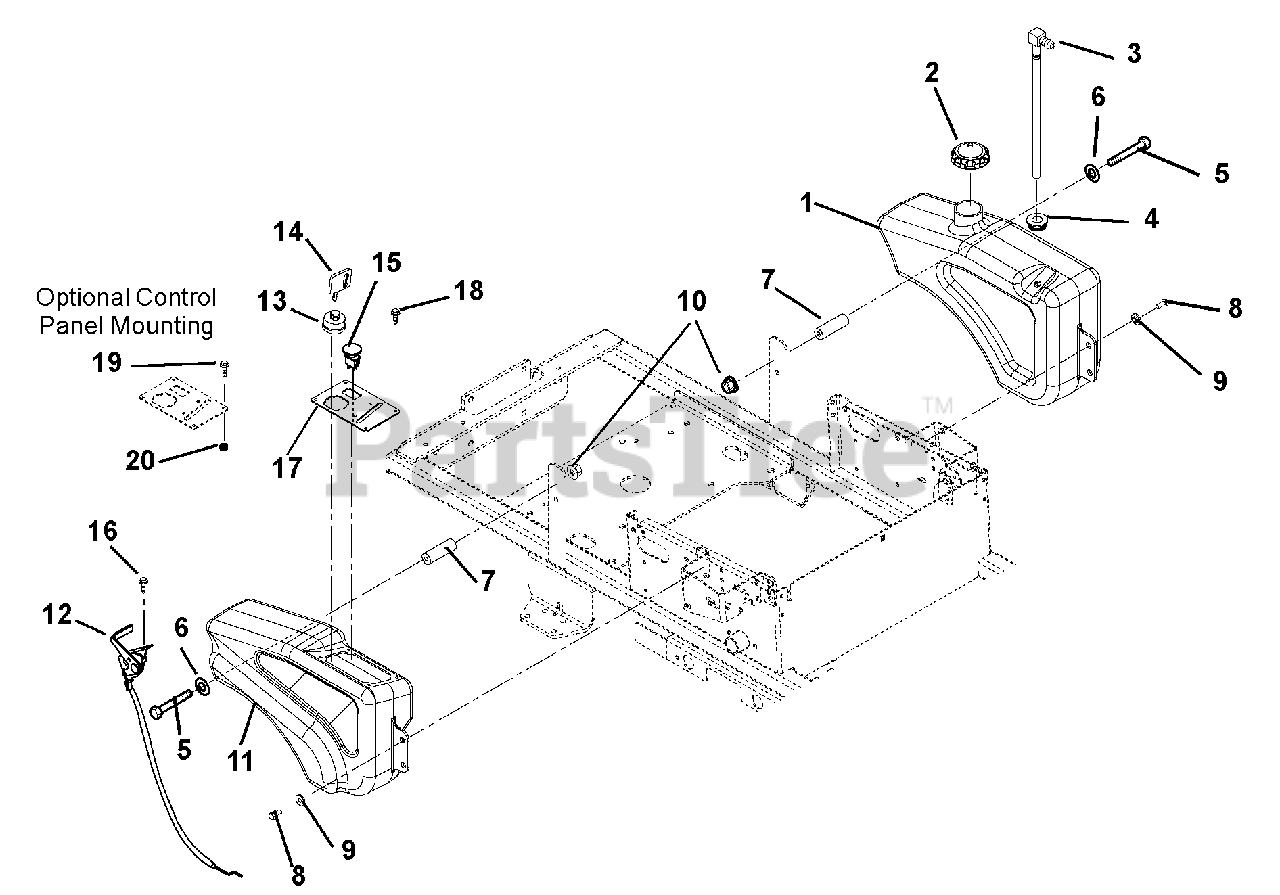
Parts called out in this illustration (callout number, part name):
1	Gas Tank
2	Fuel Cap
3	Fitting, Tank
4	Bushing, Flange .375 x 1.062 x .625
5	Bolt, Hex .31-18 x 3.50 Grade 5
6	Washer, Flat-Steel .38 x .875 x .083
7	Spacer, Tank Mount
8	Screw, Tapping .31-18 x .75 Hex Washer Head Rolling (Lubricated or Waxed)
9	Shoulder Spacer
10	Nut, .31-18 Nyloc Flange
12	Throttle/Choke Cable, 40"
13	Key Switch
14	Key, With Cap
15	Switch, Clutch
16	Screw, Tapping 10-24 x .50 Hex Washer Head Thread Rolling
17	Control Panel
18	Rivet, Plastic .195 Diameter
19	Screw, Machine 10-24 x .75 Hex Washer Head (Optional)
20	Nut, Locking Nylon 10-24 With Insert (Optional)
